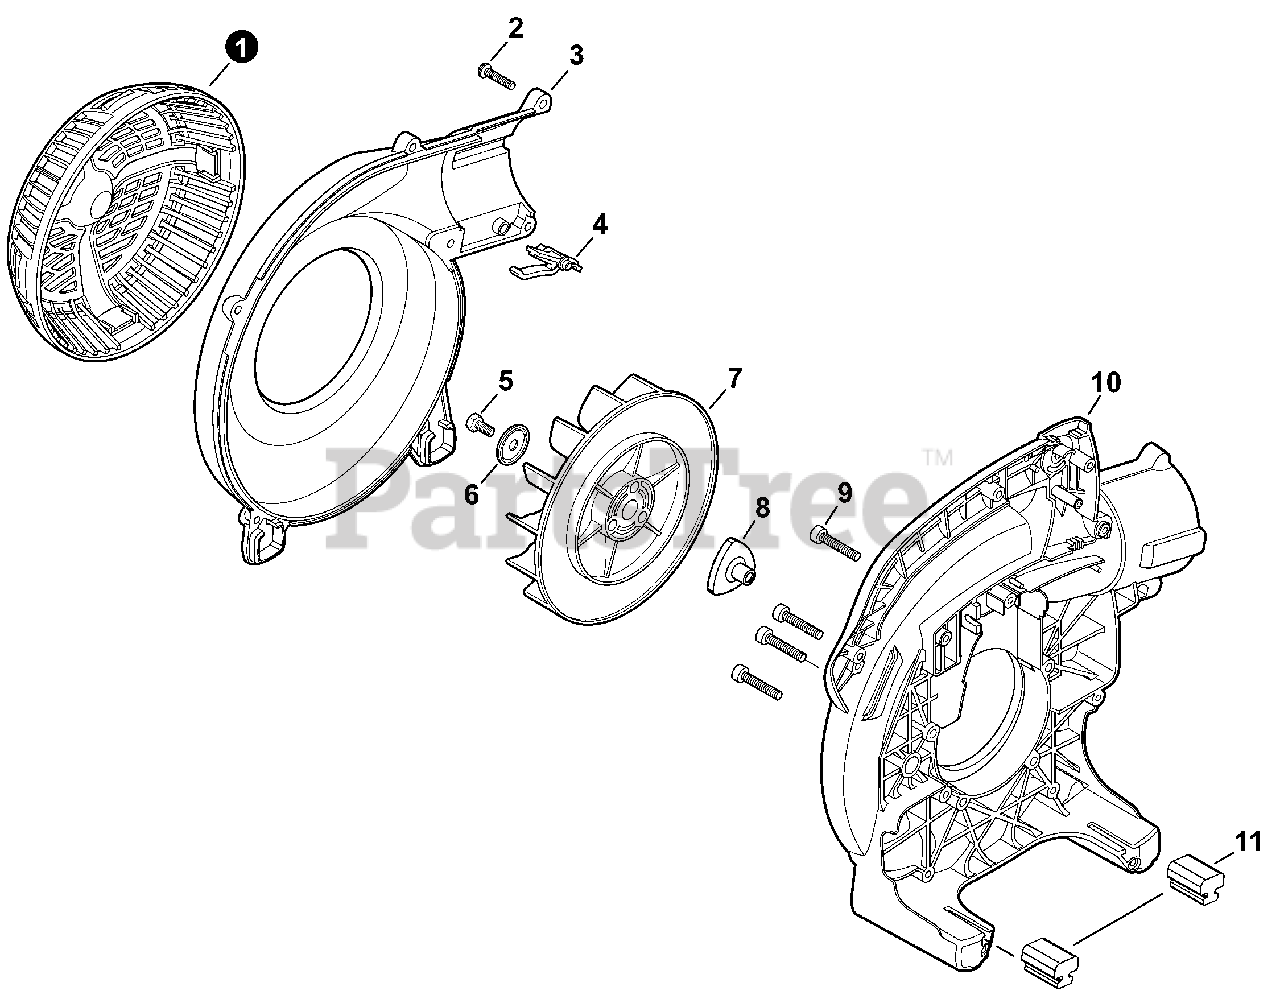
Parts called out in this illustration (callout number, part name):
1	GUARD, FAN
2	BOLT, TORX 5×20
3	COVER, FAN
4	LOCK, TUBE
5	BOLT 8×14
6	WASHER 8.2×31×0.8
7	FAN, BLOWER
8	HUB, FAN
9	BOLT, TORX 4×20
10	CASE, FAN
